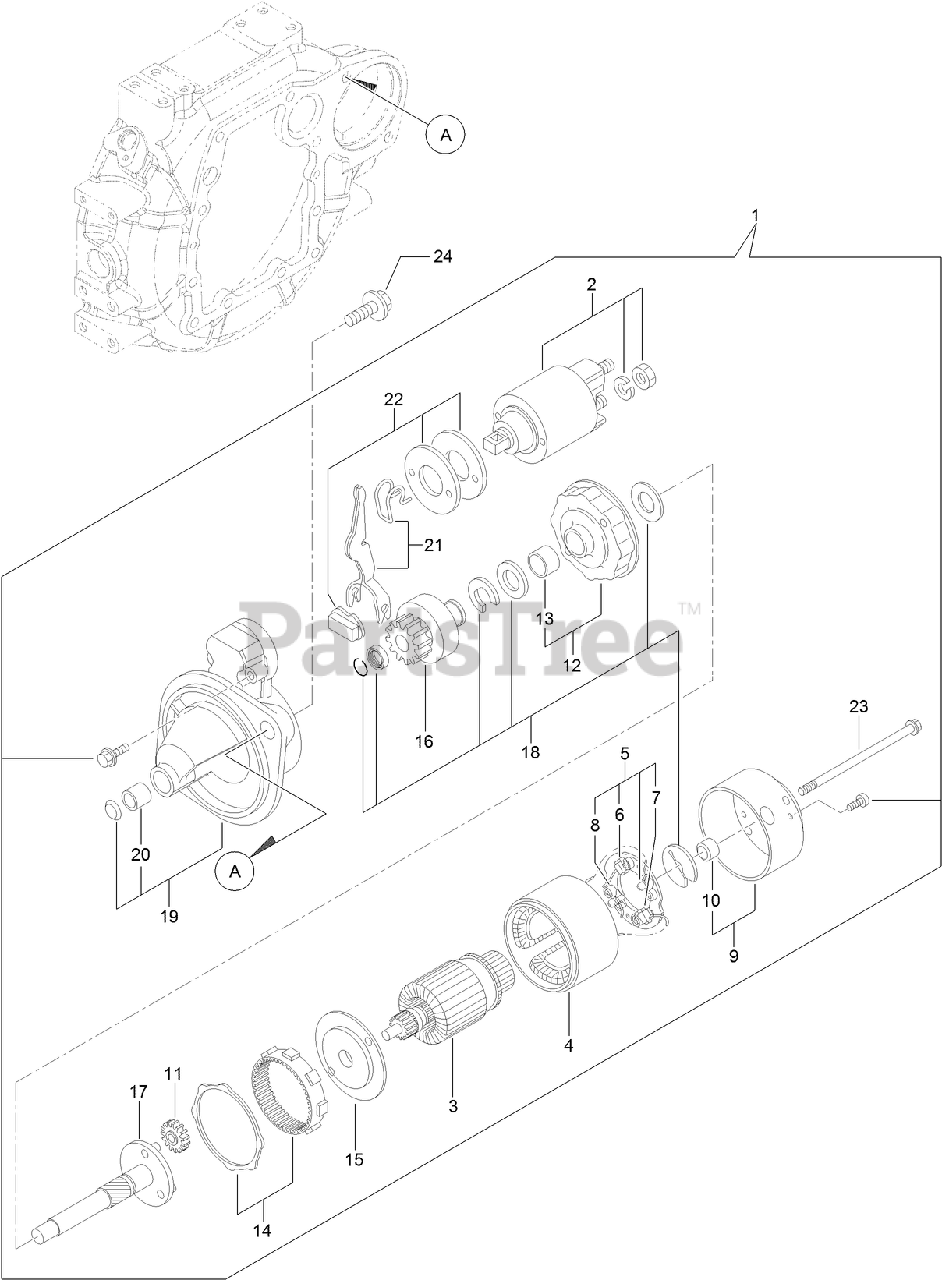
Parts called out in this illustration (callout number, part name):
1	STARTER ASM
2	SWITCH ASM
3	ARMATURE ASM
4	YOKE ASM
5	BRUSH HOLDER ASM
7	BRUSH SET
8	SPRING
9	COVER ASM
12	BRACKET
13	BRACKET
15	BRACKET
16	PINION ASM
18	WASHER SET
19	CASE ASM
20	METAL-STARTER
21	LEVER SET
22	DUST COVER ASM
23	BOLT-THROUGH
